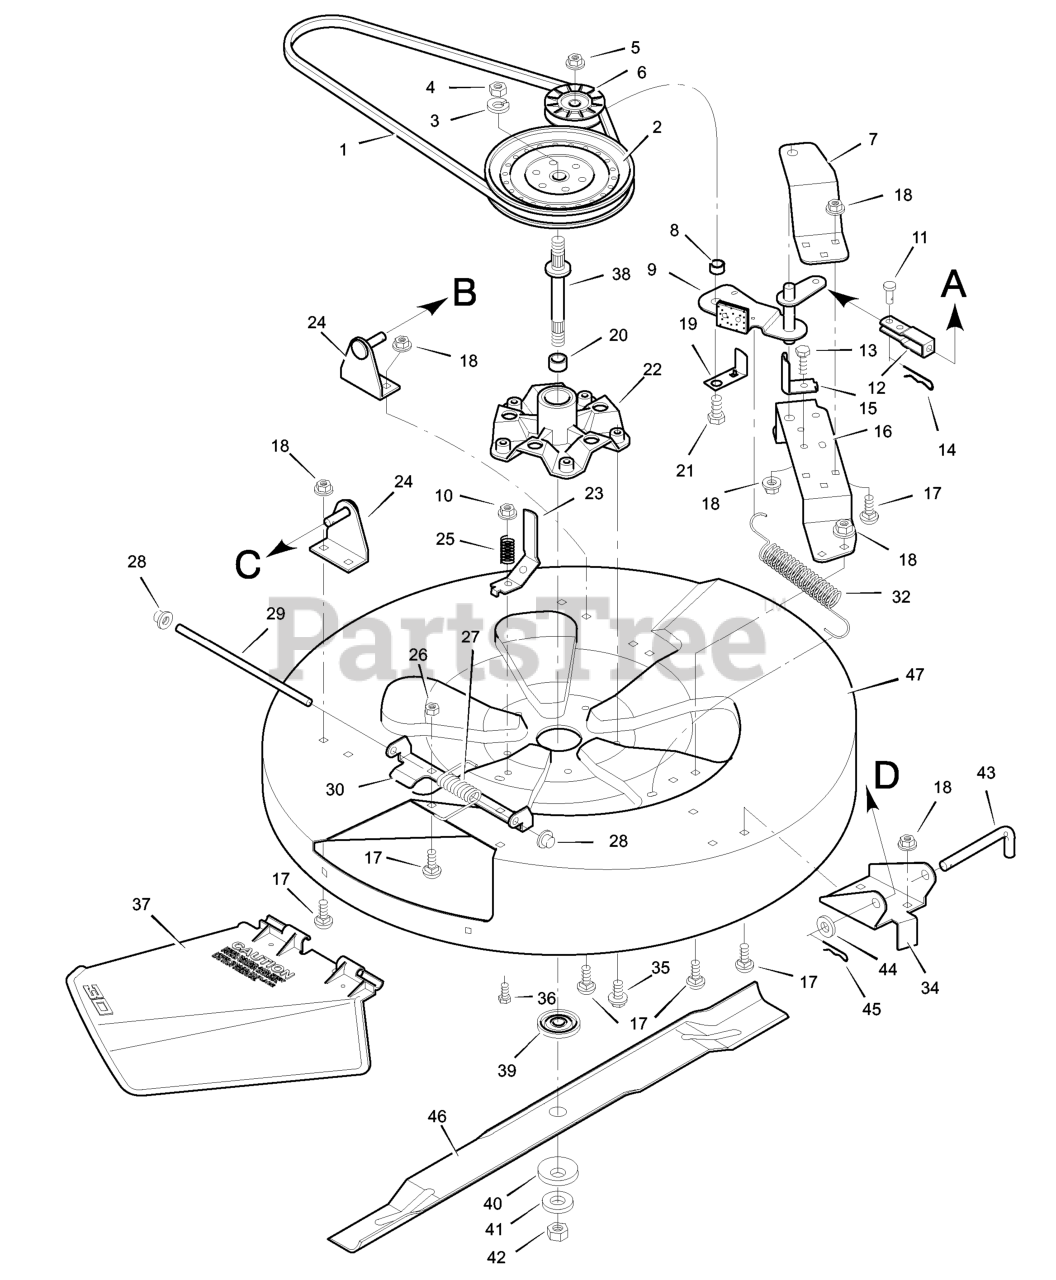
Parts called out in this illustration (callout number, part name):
1	Belt, Mower Drive
2	Pulley, Splined
3	Lockwasher
4	Locknut, Hex
5	Nut, Hex
6	Pulley, Idler
7	Bracket, Upper Idler
9	Assembly, Blade Idler
10	Locknut, Flange
11	Pin, Clevis
13	Bolt, Hex
14	Pin, Hair
15	Guide, Belt
16	Bracket, Lower Idler
17	Bolt, Carriage
18	Nut, Flange
19	Guide, Belt
21	Bolt, Hex
22	Housing, Mandrel
23	Guide, Belt
24	Bracket, Hanger
25	Spring, Compression
26	Nut, Hex
27	Spring - Torsional
28	Push On Cap
30	Hinge, Chute Deflector
32	Spring, Extension
34	Bracket, Front
36	Bolt, Hex
37	Deflector, Chute
38	Mandrel
39	Adapter, Blade
40	Washer, Belleville
41	Washer, Hardened
42	Nut, Hex
43	Pin, Pull
45	Pin, Hair
46	Blade, Standard
